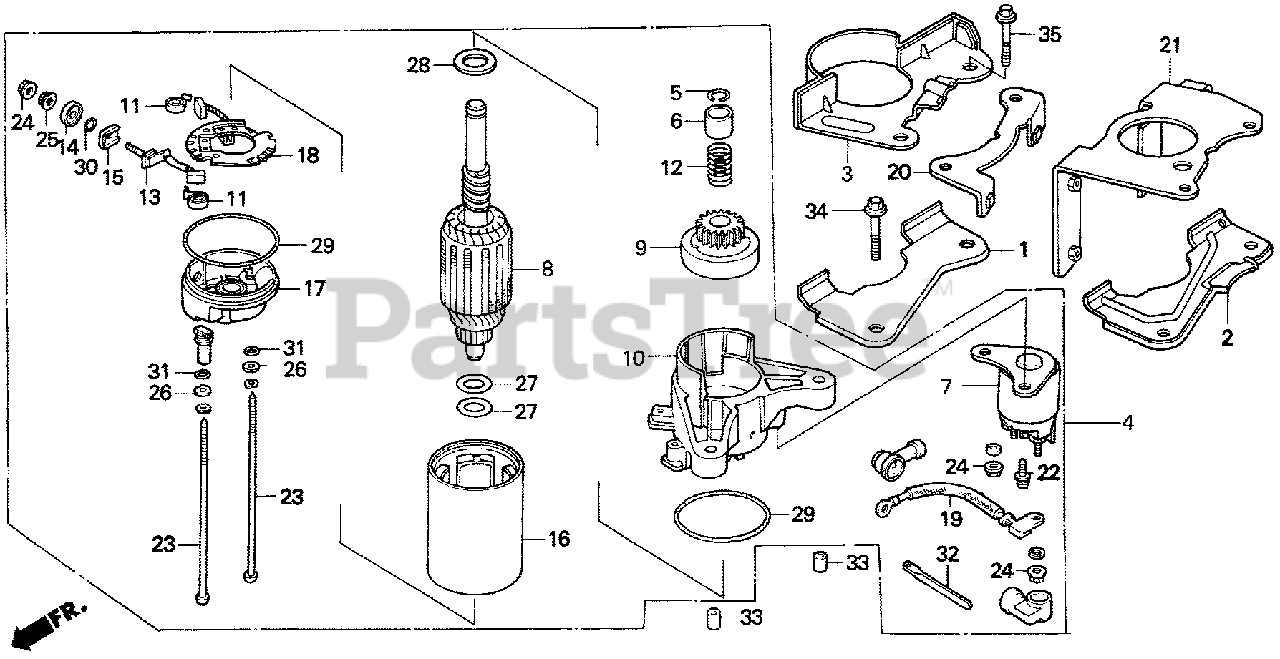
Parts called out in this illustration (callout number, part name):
3	PLATE, SIDE
21	STAY, STARTER
35	BOLT, FLANGE (8X28)
